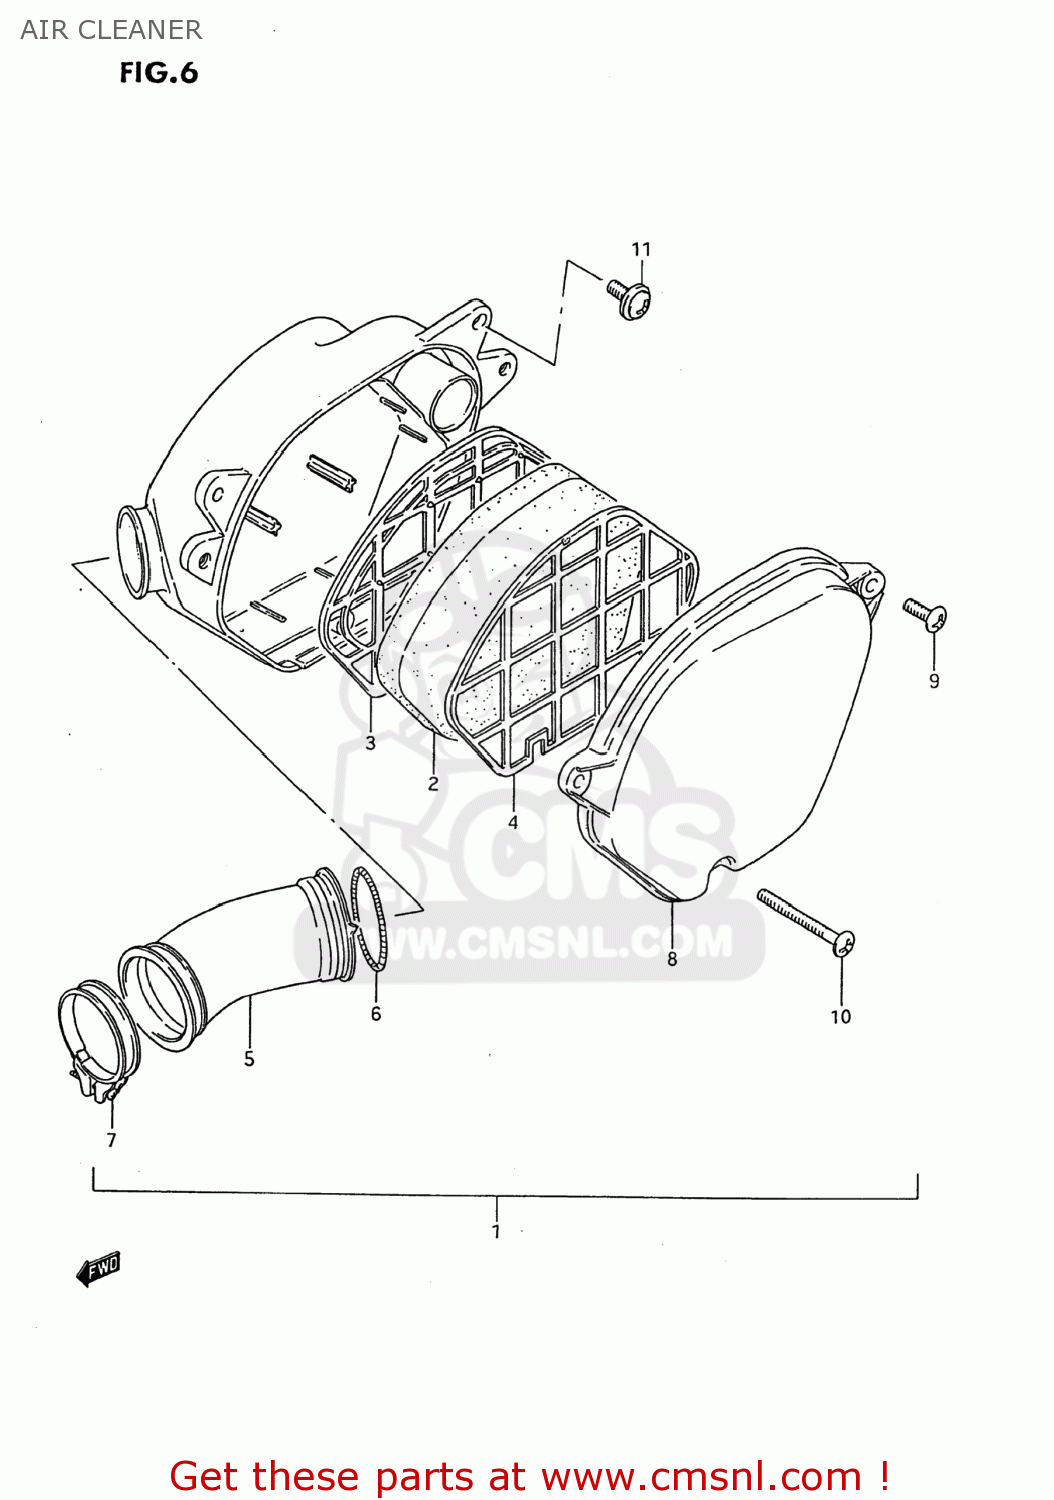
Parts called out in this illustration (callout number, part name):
1	CLEANER ASSY,AIR
2	FILTER
3	HOLDER,FILTER INNER
4	HOLDER,FILTER OUTER
5	TUBE,OUTLET
6	SPRING,AIR CLEANER SIDE
7	CLAMP
8	CAP,CLEANER
9	SCREW
10	SCREW
11	SCREW(6X16)
